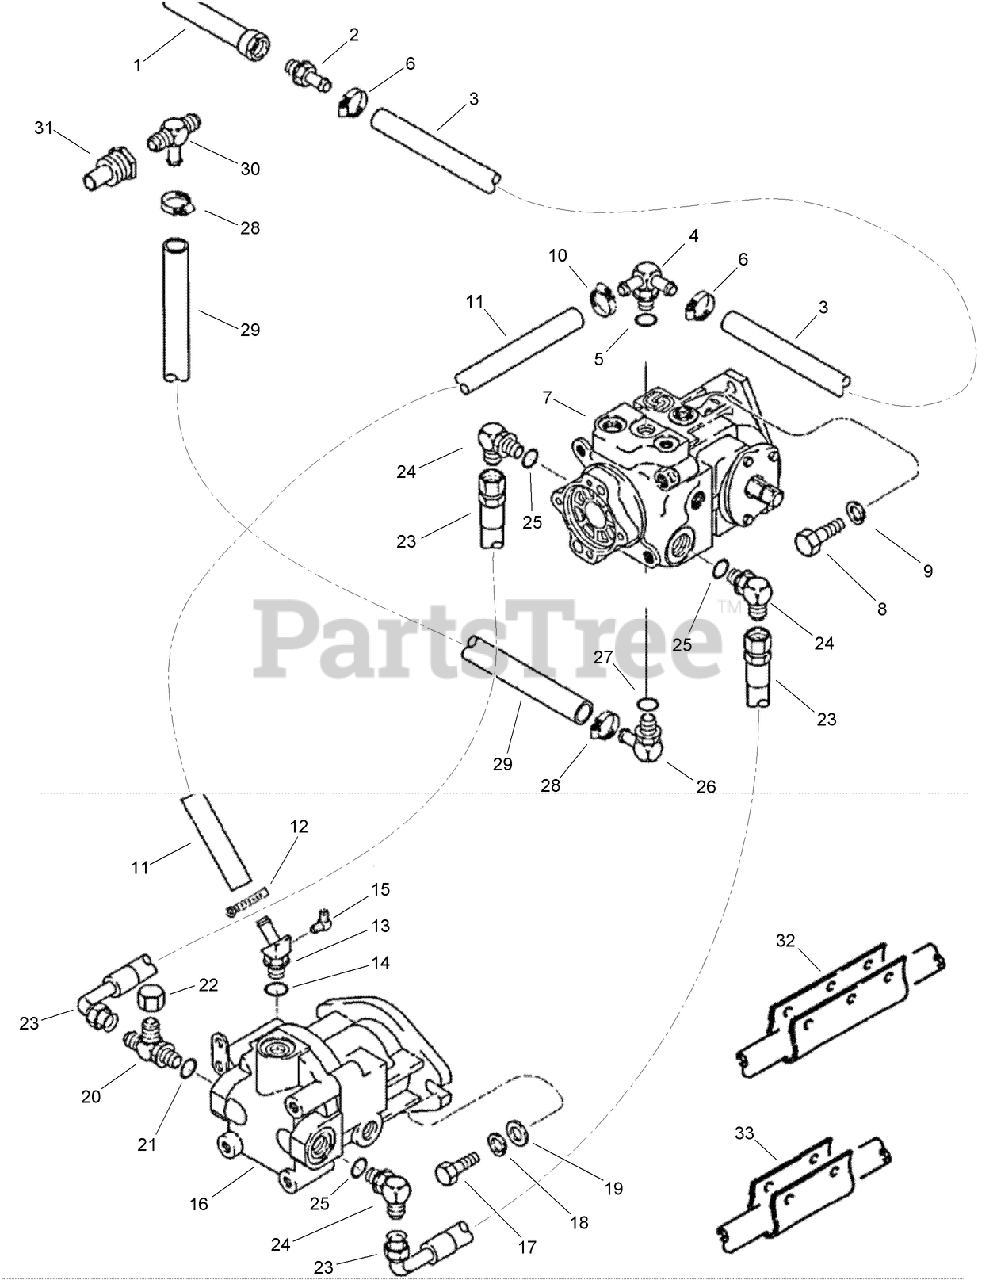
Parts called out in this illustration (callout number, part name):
1	FILTER ASM
2	FITTING-STRAIGHT
3	HOSE - 368 mm (14-1/2 inch) Long (cut from H379214 bulk hose)
5	O-RING - 59/64 ID x 7/64 inch Wide
6	CLAMP - Adj, 11/16 - 1-1/4 inch Dia
7	HYD VARIABLE PUMP ASM
8	BOLT-Hex Hd 1/2 x 1-1/4 GR5 ZND
9	WASHER-Spring Lock Reg 1/2 ZND
10	CLAMP - Adj, 11/16 - 1-1/4 inch Dia
11	HOSE - 800 mm (31-1/2 in), Return, Steering Control Valve to Dual Pump
12	CLAMP - Adj, 11/16 - 1-1/4 inch Dia
13	FITTING - 45 degree, Special
14	O-RING
15	ELBOW - 90 Degree, 9/16-18 flare x 1/4 inch PT
16	MOTOR ASSEMBLY - Ground Drive
17	BOLT-Hex Hd 1/2 x 1-1/4 GR5 ZND
18	WASHER-Spring Lock Reg 1/2 ZND
20	TEE - 1-1/16-12 inch Adj O-Ring Branch x Flare x Flare
21	O-RING - 59/64 ID x 7/64 inch Wide
23	HOSE - 660 mm (26 inch) Long, Ground Drive Pump to Ground Drive Motor
24	ELBOW-90 Adj 37FL 3/4 Tube
25	O-RING - 59/64 ID x 7/64 inch Wide
26	ELBOW - 90 Degree, 3/4 Stem End x 1-5/16-12 inch Adj O-Ring
27	O-RING - 1-11/64 ID x 7/64 inch Wide
28	CLAMP - Adj, 11/16 - 1-1/4 inch Dia
29	HOSE - 457 mm (18 inch) Long Ground Drive Pump to Reservoir (cut from D55911 bulk hose)
30	FITTING-ELBOW, LATERAL
31	INDUCER-PRESSURE
32	BOOT-HOSE
33	BOOT-HOSE
